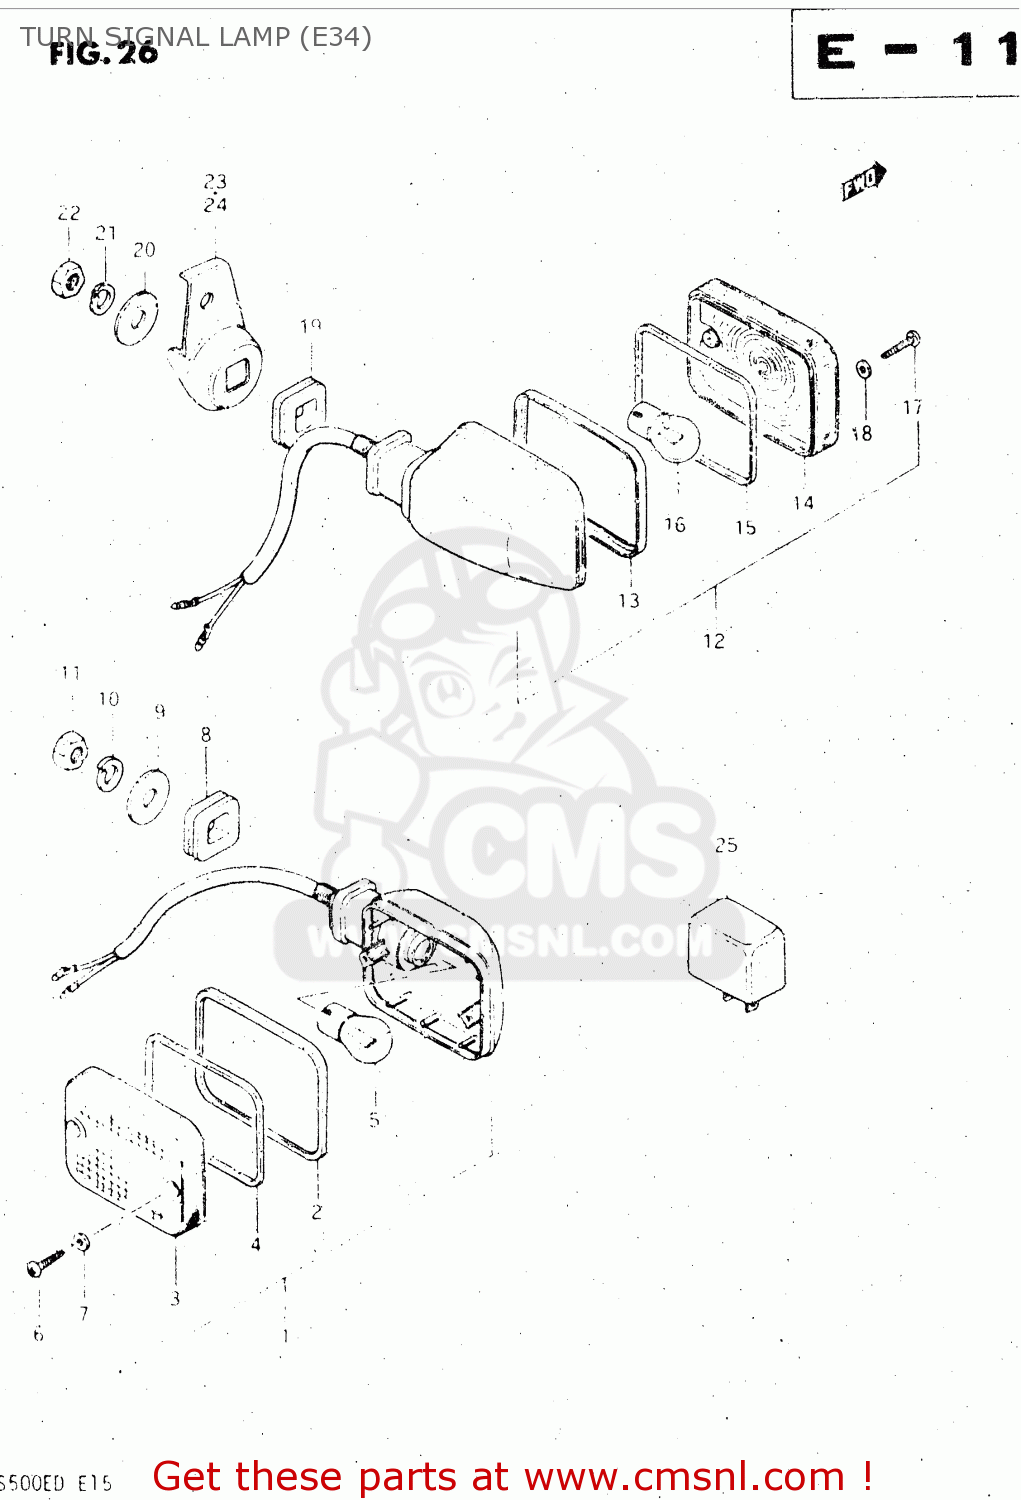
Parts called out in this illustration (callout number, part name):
1	LAMP ASSY,FR T
2	RIM
3	LENS
4	GASKET (NAS)
5	BULB(12V21W)
6	SCREW
7	GASKET
8	CUSHION
9	WASHER (10.5X30X2.3)
10	LOCK WASHER
11	NUT
12	LAMP, REAR TURN SIGNAL
13	RIM
14	LENS
15	GASKET (NAS)
16	BULB(12V21W)
17	SCREW
18	GASKET (NAS)
19	CUSHION
20	WASHER (10.5X30X2.3)
21	LOCK WASHER
22	NUT
23	BRACKET,REAR TURN SIGNAL
24	BRACKET,REAR TURN SIGNAL
25	RELAY,TURN SIGNAL
